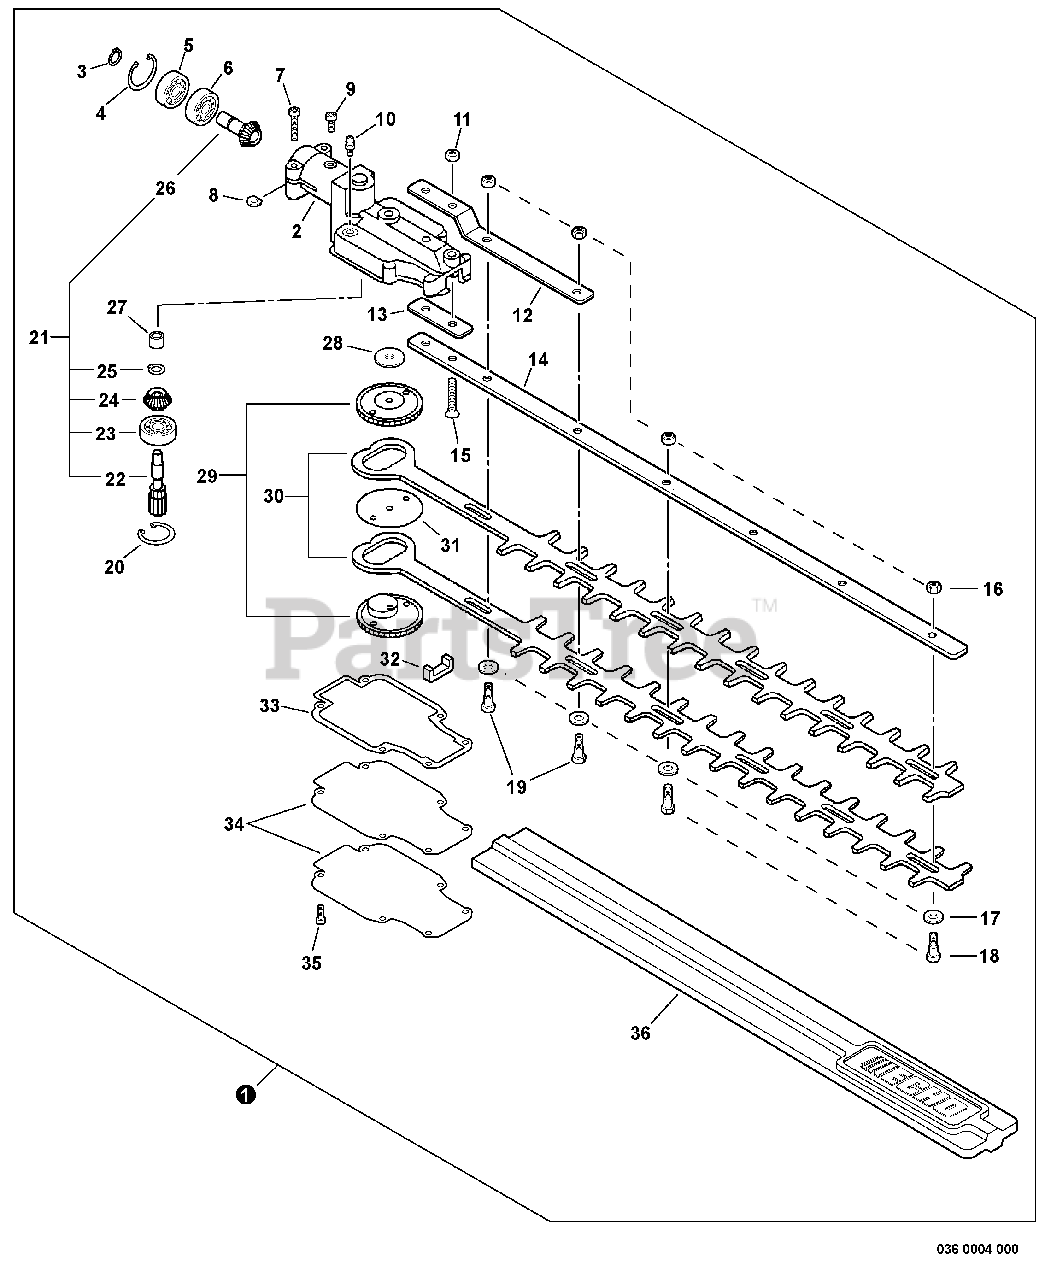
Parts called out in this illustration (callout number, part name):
1	GEAR CASE ASSY
2	CASE, GEAR - UPPER
3	RING, SNAP Ø12
4	RING, RETAINING Ø24
5	BEARING, BALL 6901Z
6	BEARING, BALL 6901
7	BOLT 5×28
9	BOLT, TORX 5×12
10	FITTING, GREASE
11	NUT, HEX M6
12	PLATE, ANGLE
13	SPACER
14	SUPPORT, BLADE
15	SCREW 6×35
17	WASHER 6.5×15.5×0.6
19	BOLT 6×20
20	RING, RETAINING Ø24
21	GEAR KIT, SPUR
22	GEAR, PINION
23	BEARING, BALL 6901
24	GEAR, BEVEL
25	RING, RETAINING
26	GEAR, BEVEL
27	BEARING, NEEDLE
28	WASHER 6.5×30×0.2
29	GEAR, SPUR
31	WASHER 6.7×54×0.38
33	GASKET, GEAR CASE
34	LID, GEAR CASE
35	BOLT, TORX 4×12
36	SCABBARD
